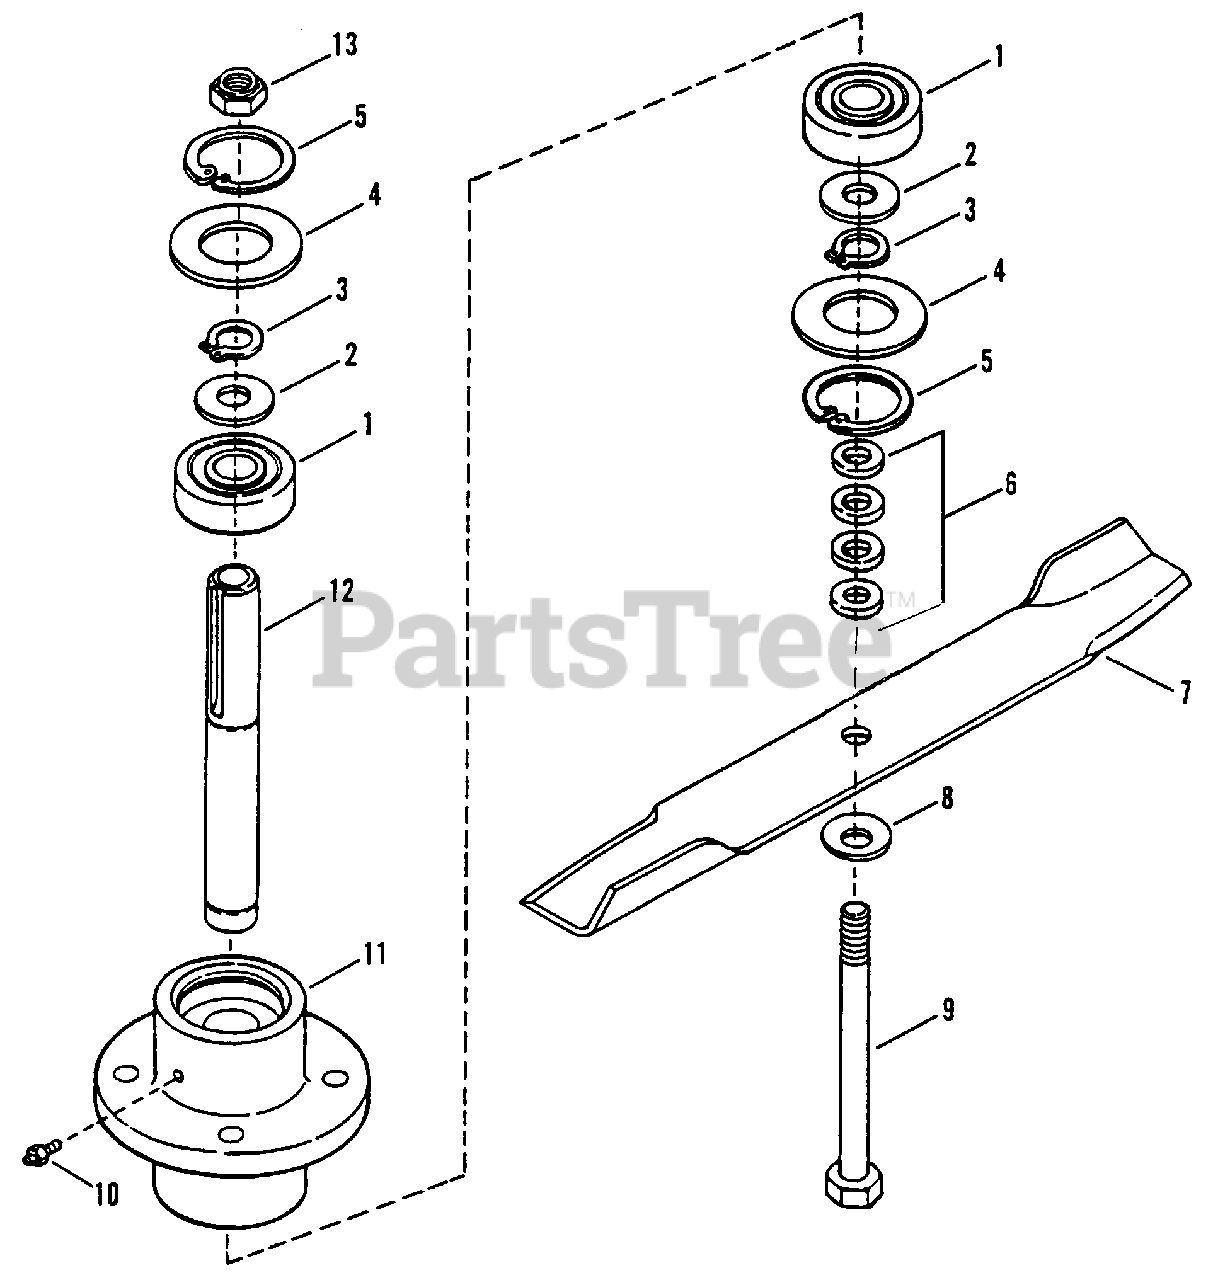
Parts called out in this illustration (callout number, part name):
1	BEARING, Sealed
2	WASHER, Spindle
3	SNAP-RING, Spindle Shaft
4	WASHER, Spindle Housing
5	SNAP-RING, Spindle Housing
6	SPACER, Blade
7	BLADE, 18", High Lift
8	WASHER, Beveled
9	BOLT, 5/8-18 x 9-3/4" Hex Head Cap Gr. 5
10	FITTING, Lube
11	HOUSING, Cutter
12	SHAFT, Spindle
13	NUT, 5/8-18 Hex
